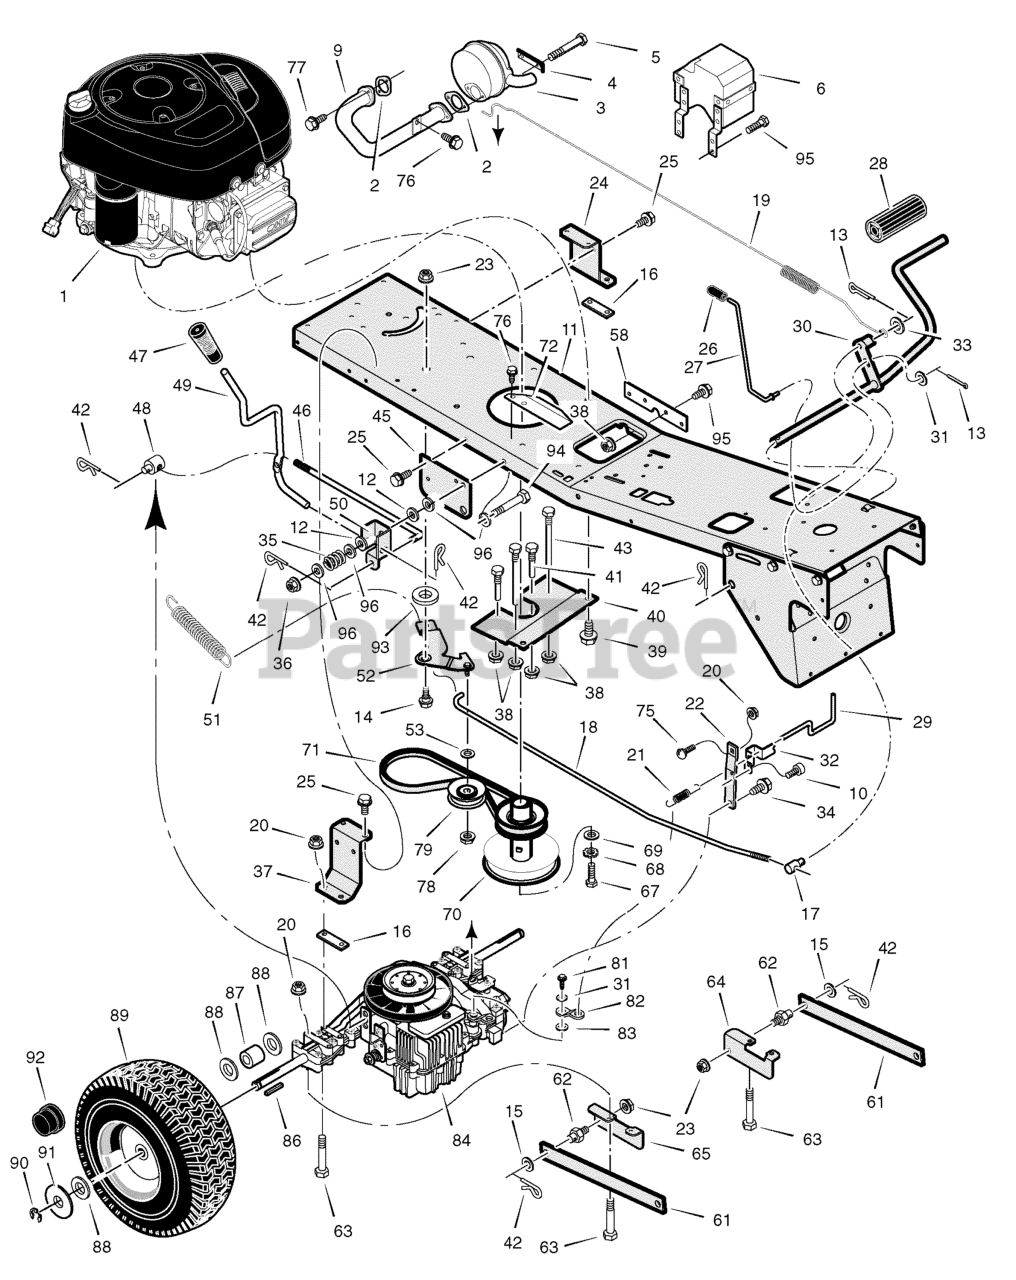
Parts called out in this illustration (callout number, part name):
1	Engine
1	Engine, Plenum
2	GASKET, Exhaust
3	Muffler
4	Lock, Muffler Screw
5	Bolt, Hex
6	Shield, Heat
9	Tube, Exhaust
10	Screw
12	Washer
13	Pin, Cotter
14	Bolt, Shoulder
15	Washer
16	Plate, Transaxle
17	Nut, Adjusting
18	Rod, Clutch Hydro
19	Spring, Brake
20	Nut
21	Spring, Roll Release
22	Bracket, Torque Strap
23	Nut
24	Bracket, Left Transaxle
25	Screw
27	Rod, Parking Brake
28	Pedal
29	Rod, Roll Release
30	Rod, Clutch/Brake
31	Washer
32	Bracket, Roll Release
33	Washer
34	Screw
35	Spring, Compression
37	Bracket, Right Transaxle
39	Screw
40	Plate, Belt Guide
41	Guide, Belt -Long
42	Pin, Hair
43	Guide, Belt -Short
45	Bracket, Lift Pivot
46	Rod, Shift Link
47	Grip
48	Nut, Adjusting
49	Lever, Shift
50	Bracket, Pivot
51	Spring - Variator Drive
52	Arm, Idler
53	Washer
58	Plate, Reinforcement
61	Arm, Rear
62	Pin, Threaded
63	Bolt, Hex
64	Bracket, Left Rear Hanger
65	Bracket, Right Rear Hanger
67	Bolt, Hex
68	Lockwasher
69	Washer
70	Pulley Stack
71	Belt, Drive
72	Shield, Heat
75	Bolt, Carriage
76	Screw
77	Screw
78	Locknut
79	Pulley, Idler
81	Cap Screw
82	ARM, Disconnect
83	Washer
84	Transaxle
86	Key, Square
87	SPACER, Rear Wheel
88	Washer
89	Wheel & Tire Assembly
90	E-Ring
91	Washer
92	Hub Cap
93	Washer
94	Bolt, Hex
95	Screw
96	Washer
